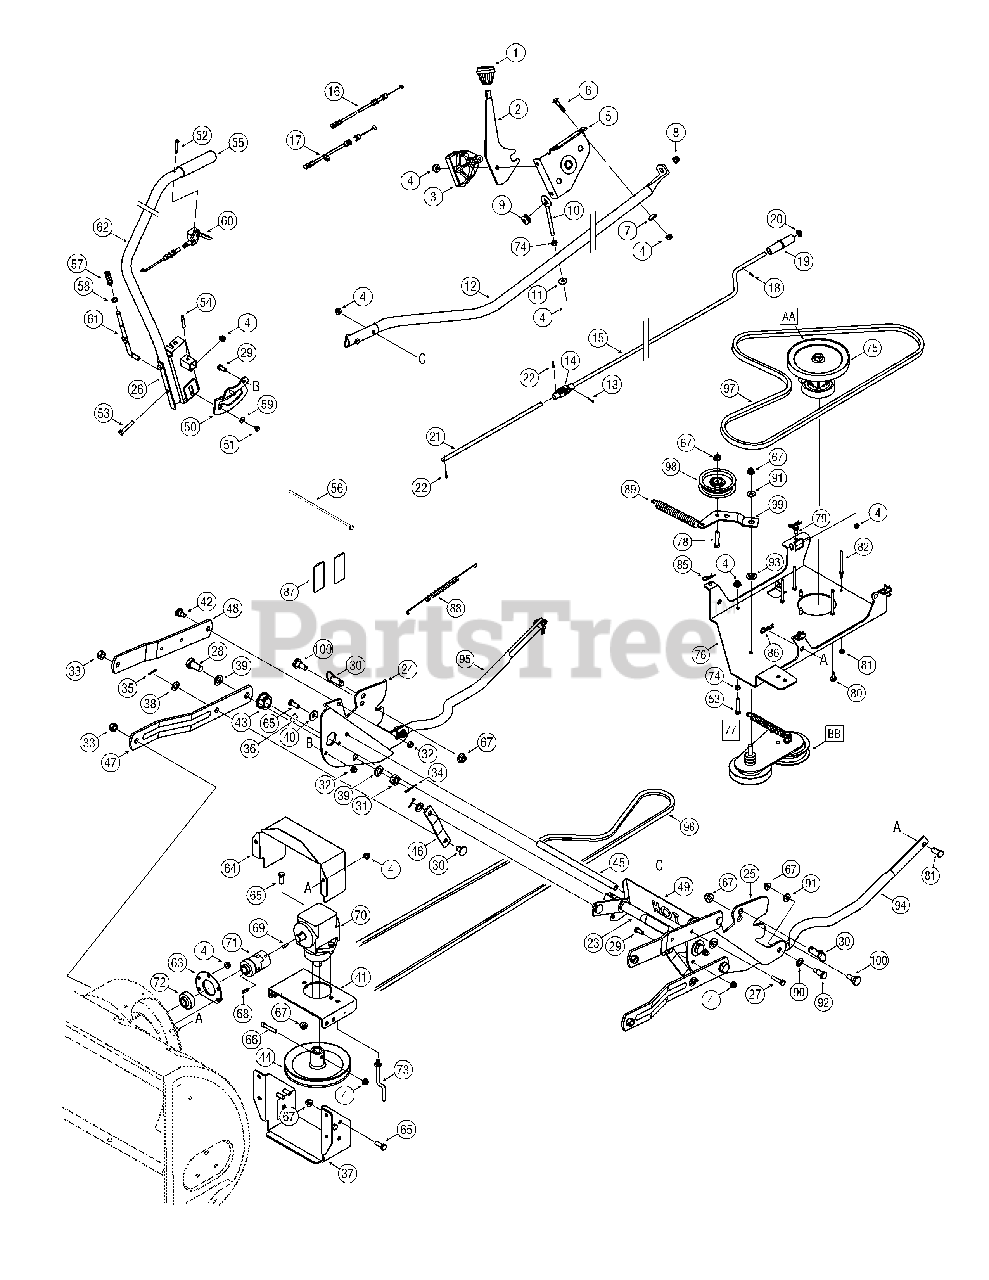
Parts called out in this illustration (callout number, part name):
2	Chute Tilt Handle
3	Chute Tilt Cable Guide
4	Nylon Hex Lock Nut, 5/16-18
5	Chute Tilt Bracket Assembly
6	Carriage Bolt, 5/16-18 x 1.5
7	Saddle Washer, .32 x .93
8	Plastic Bushing
9	Rubber Grommet, .44 x .94 x .5
10	Eye Bolt
11	Bell Washer, .340 x .872
12	Support Chute Tube
13	Cotter Pin, 3/32 x .75
14	Joint Block Assembly
15	Chute Crank Rod, .375 x 33
16	Chute Cable, 62''
17	Chute Cable w/Clip, 62''
18	Rolled Pin, 1/8 x .63
19	Crank Knob
20	Push Cap, 3/8 ID
21	Rod, .375 x 11.375
22	Spirol Pin, .125 x .82
23	Rod Assembly
24	RH - Support Plate Assembly
25	LH - Support Plate Assembly
27	Hex Cap Screw, 5/16-18 x 1.50
28	Hex Cap Screw, 5/8-18 x 1.31
29	SCREW 5/16-18 x .75 GR5
30	Clevis Pin, .5 x .78
31	Slotted Hex Nut, 5/8-18
32	Hex Lock Nut, 3/8-16
33	Hex Lock Nut, 1/2-13
34	Cotter Pin, 1/8 x 1.25
35	Cotter Pin, .125 x .75
36	Snap Ring
37	Skid Plate
38	Flat Washer,.51 x 1.0 x .060
39	Flat Washer, .64 x 1.12 x .125
40	Bell Washer, .396 x 1.14 x .095
41	Drive Mounting Bracket
42	Shoulder Screw, .5 x .29, 3/8-16
43	Flange Bearing w/ Flats
44	Drive Pulley, 7''
45	Rod, 1/2 x 11.55
46	Link, 5.875
47	Link, 15.4
48	Link, 13.35
49	Heat Shield
50	Snow Thrower Lift Bracket
51	Hex Index Washer Screw #10-16
52	Pan Phillips Screw, #10-24 x .75
53	Hex Cap Screw, 5/16-18 x 1.75
54	Heavy Duty Spirol Pin, 1/4 x 1.5
55	Handle Grip
56	Cable Tie
57	Compression Spring
58	Flat Washer, .385 x .62 x .063
59	Flat Washer, .194 x .62 x .063
60	Lift Cable, 42'' w/Trigger Control
61	Lift Index Rod
63	Bearing Housing, 1.85 ID
65	Hex Cap Screw, 3/8-16 x 1.0
66	Socket Head Cap Screw
67	Flange Lock Nut, 3/8-16
68	Square Key, 3/16 x .75
69	Hi-Pro Key, 3/16 x .75
70	Right Angle Drive
71	Coupling
72	Flange Ball Bearing, .75 x 1.85
73	Belt Keeper Rod
74	Flange Nut, 5/16
75	Spindle Assembly
76	Pulley Mounting Bracket
77	Double Idler Bracket Assembly
78	Hex Cap Screw, 3/8-16 x 1.75
79	Pin, 5/16-18
80	Screw, 5/16-18 x .75
81	Clevis Pin, .5 x 1.18
82	Belt Keeper Pin
83	Nylon Hex Lock Nut, 1/4-20
84	Wing Nut 5/16-18
85	Click Pin, .092 x 1.64
86	Internal Cotter Pin, .125 x 1.75
87	Reflector
88	Extension Spring, .50 x 12.00
89	Extension Spring, .91 x 7.33
90	Flat Washer.531 x .93 x .09
91	Flat Washer, .38 x .93 x .11
92	Shoulder Screw, 3/8-16
93	Shoulder Spacer, .625 x .169
94	LH - Support Tube
95	RH - Support Tube
96	V-Belt (1/2 x 105)
97	V-Belt (A Sec. x 66.90)
98	Idler Pulley 3.50 Dia
99	Idler Bracket
100	SHOULDER SCREW .498 DIA x .340
